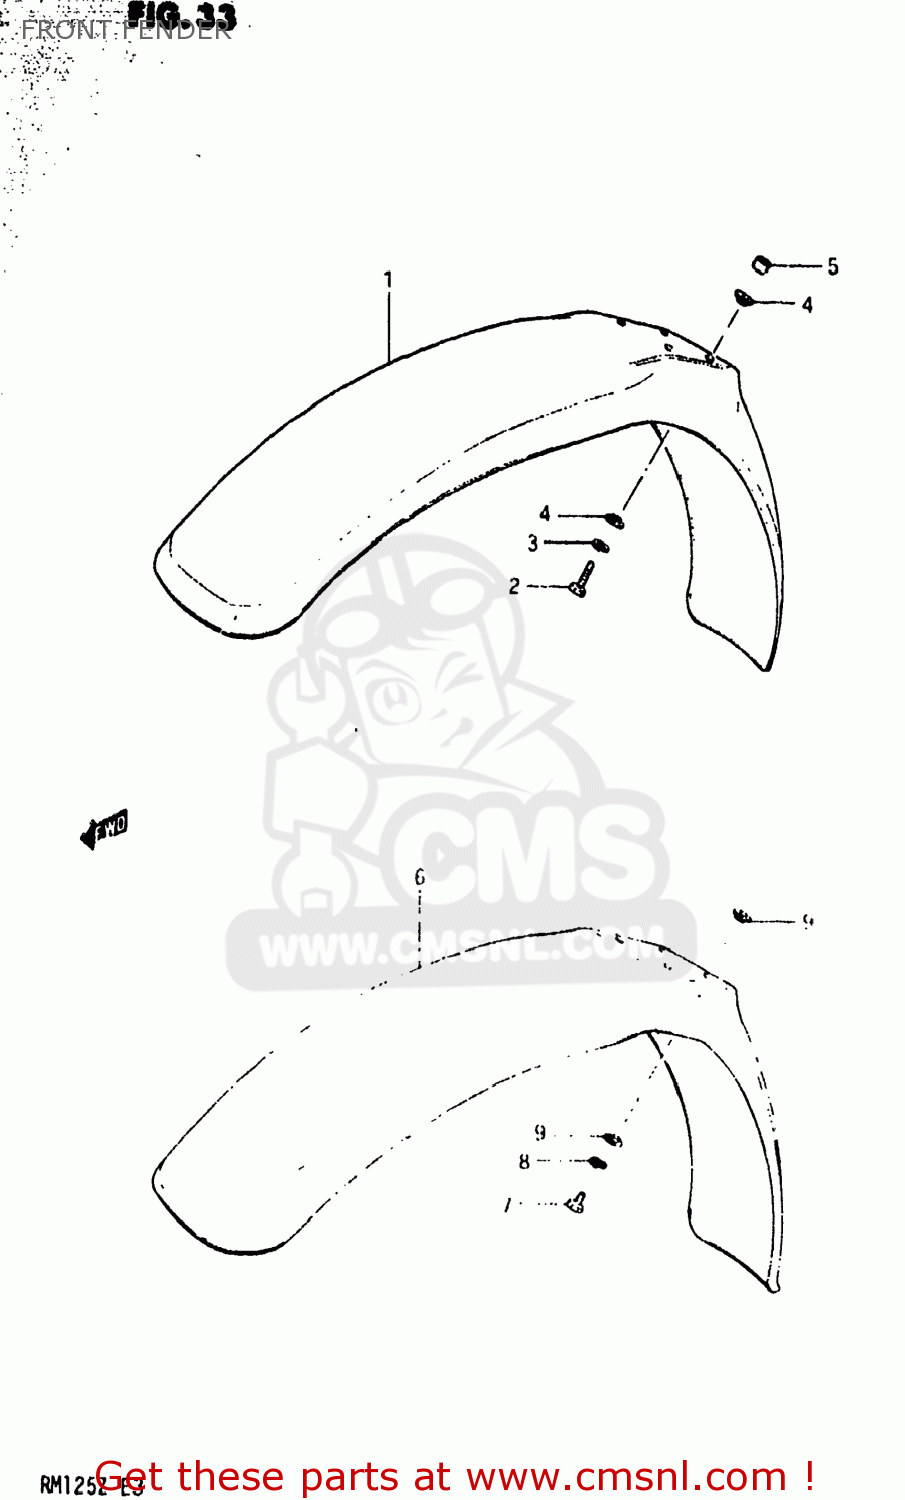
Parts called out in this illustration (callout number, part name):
1	FENDER,FRONT
2	BOLT
3	LOCK WASHER
4	WASHER
5	SPACER,FRONT FENDER
6	FENDER,FR
7	BOLT, UPPER
8	LOCK WASHER
9	SPACER
